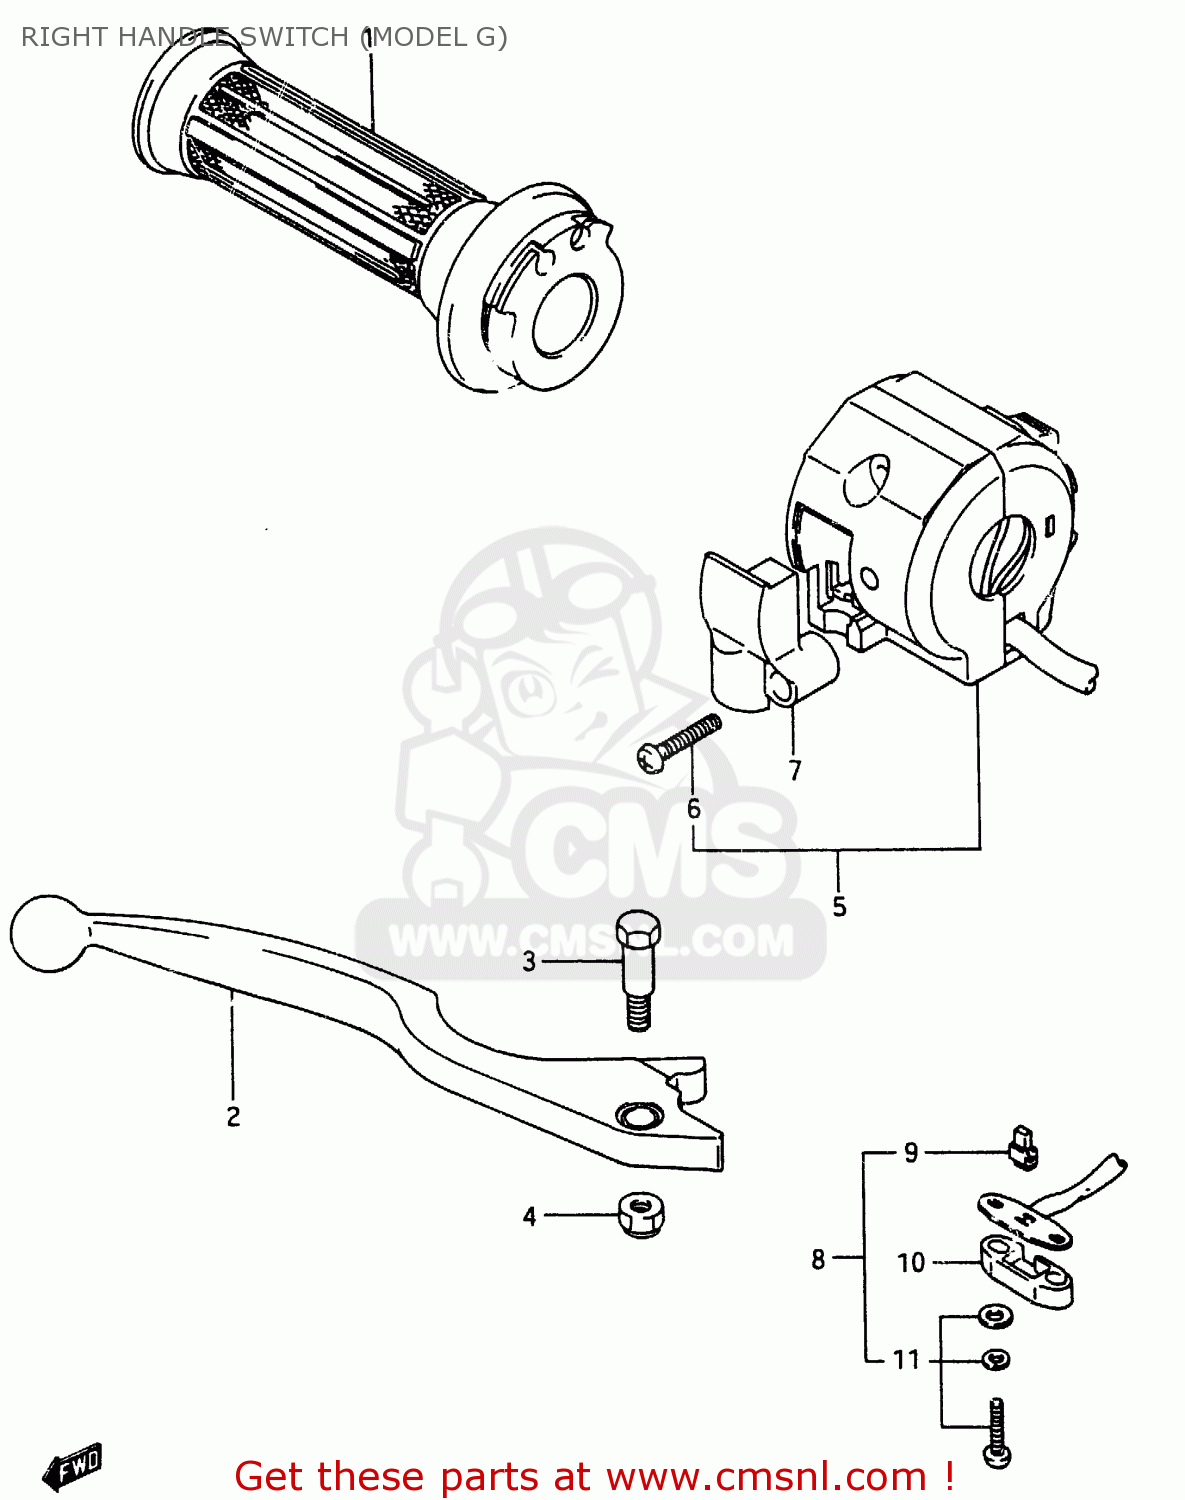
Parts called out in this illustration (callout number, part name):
1	GRIP,THROTTLE
2	LEVER,BRAKE
3	BOLT,LEVER PIVOT
4	NUT
5	SWITCH ASSY, HANDLE RH
6	SCREW 5X20
7	COVER
8	SWITCH ASSEMBLY
9	CONTACT,SWITCH
10	COVER,FR BK TERMINAL BASE
11	SCREW
